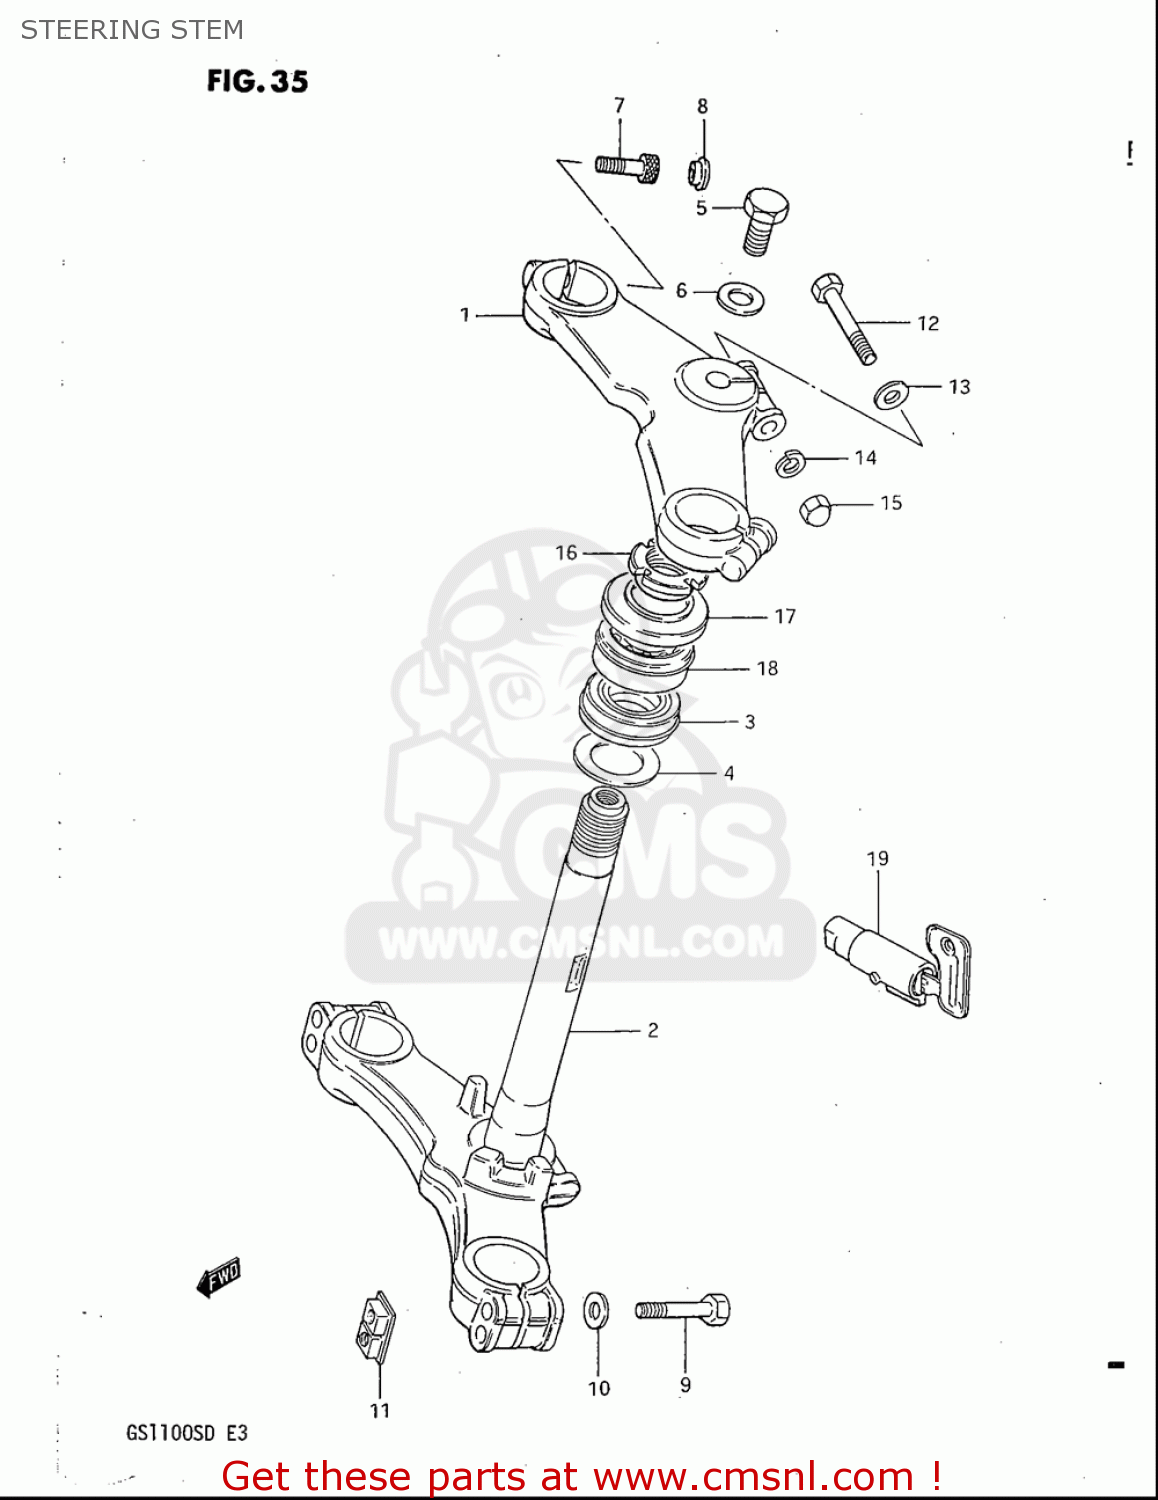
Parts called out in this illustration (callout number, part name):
1	HEAD,STEERING STEM
3	BEARING(30X55X17)
4	SHIM(30X40X1.5)
5	BOLT
6	WASHER,STEERING STEM
8	CAP(OD:20)
9	BOLT
10	WASHER
11	NUT,FR FORK INNER TUBE
12	BOLT
13	WASHER
14	WASHER,LOCK
15	NUT
16	NUT,STEERING STEM
17	DUST SEAL,STEERING UPR
18	BEARING(25X47X15)
19	LOCK ASSEMBLY,STEERING (NEI
